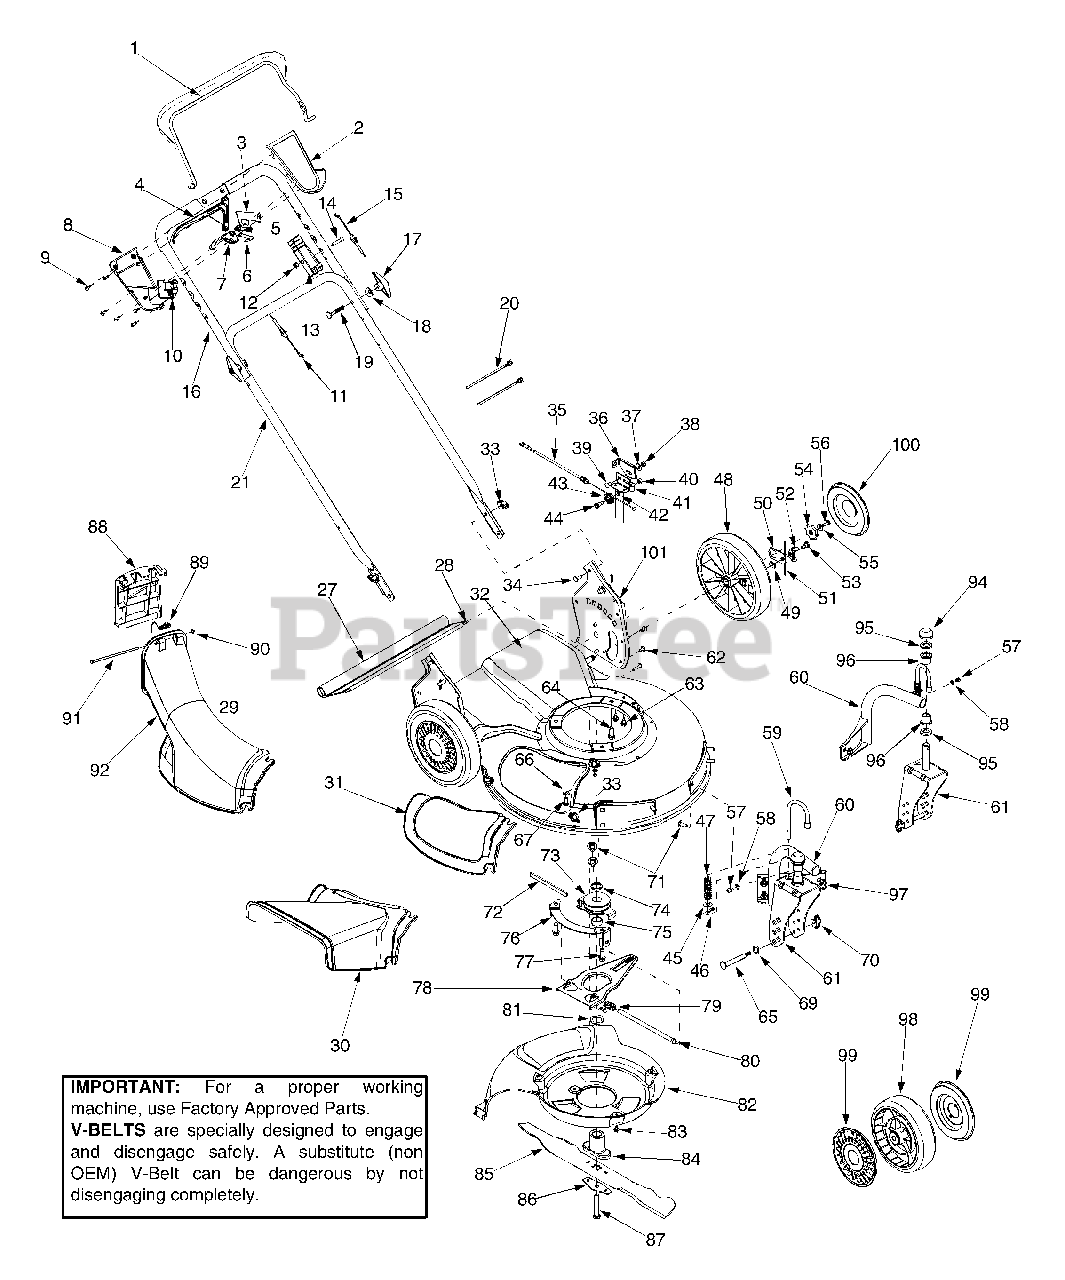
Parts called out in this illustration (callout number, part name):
1	Control Handle
2	Upper Control Handle
3	6 Sped. Rack Cable Bracket
4	Control Lever
5	Gear Insert
6	Shift Lever Spring
7	6 Speed Shift Lever
8	Lower Control Housing
9	C Sunk Tap Screw #10 x.75 Leg
10	Cable Mounting Cap
11	Drive Cable 51"
12	Top Lock Nut 1/4-20
13	Control Housing
14	Oval C-Sunk Screw
15	Control Cable 55"
18	Saddle Washer.320 ID x.830 OD
19	Carriage Bolt 5/16-18 x 2.0
20	Cable Tie
28	Trail Shield Wire
29	Chute Assembly
30	Side-Discharge Chute
31	Mulch Cover
34	Carriage Bolt 1/4-20 x.75
35	6 Speed Cable
38	Hex Nut 1/4-20
39	Carriage Screw 1/4-20 x.50
40	Hex Nut 1/4-28
43	Roller Cable
44	Shoulder Screw.375 ID x 1/4-14
45	Flat Washer.330 ID x.630 OD
47	Compression Spring
48	Wheel 9 x 2
49	Top Lock Tab Weld Nut 1/4-20
50	Ratchet Pawl Plate
51	Plastic Spring Ratchet
53	Sold Screw.340 ID x.285 OD
54	Wheel Ratchet
55	Bell Washer.265 ID x.75 OD
56	Hex Cap Screw 1/4-20 x.620
57	Grease Fitting
58	Flat Washer.203 ID x.403 OD
59	Wheel Pin Lock
62	Screw 1/4-14 x.500
63	Screw 1/4-14 x.625
64	Hex Washer Screw 3/8-16 x 1.0
65	Caster Axle
66	Flat Washer.344 ID x.62 OD
67	Carriage Screw 1/4-20 x.75
69	Wave Washer.531 ID x.781 OD
70	Wing Nut
71	Carriage Bolt 5/16-18 x.62
72	Belt 3/8 x 39.24
73	Pulley Assembly
74	Sleeve Spacer.88 ID x 1.13 OD
75	Sleeve Spacer.88 ID x 1.00 OD
77	Screw 3/8-18 x 1.0
81	Wave Washer 1.38 ID x.88 OD
82	Baffle
83	Screw 1/4-20 x 3.75
84	Blade Adapter Kit
85	21" Mulching Blade
86	Blade Bell Support
87	Hex Bolt 3/8-24 x 2.5
88	Chute Door
89	Torsion Spring
92	Discharge Chute
95	Flat Washer.640 ID x 1.12 OD
96	Flange Bearing
97	Flange Lock Nut 5/16-18
99	Hubcap - Spoke w/ Hole
100	Hubcap - Radial Spoke
